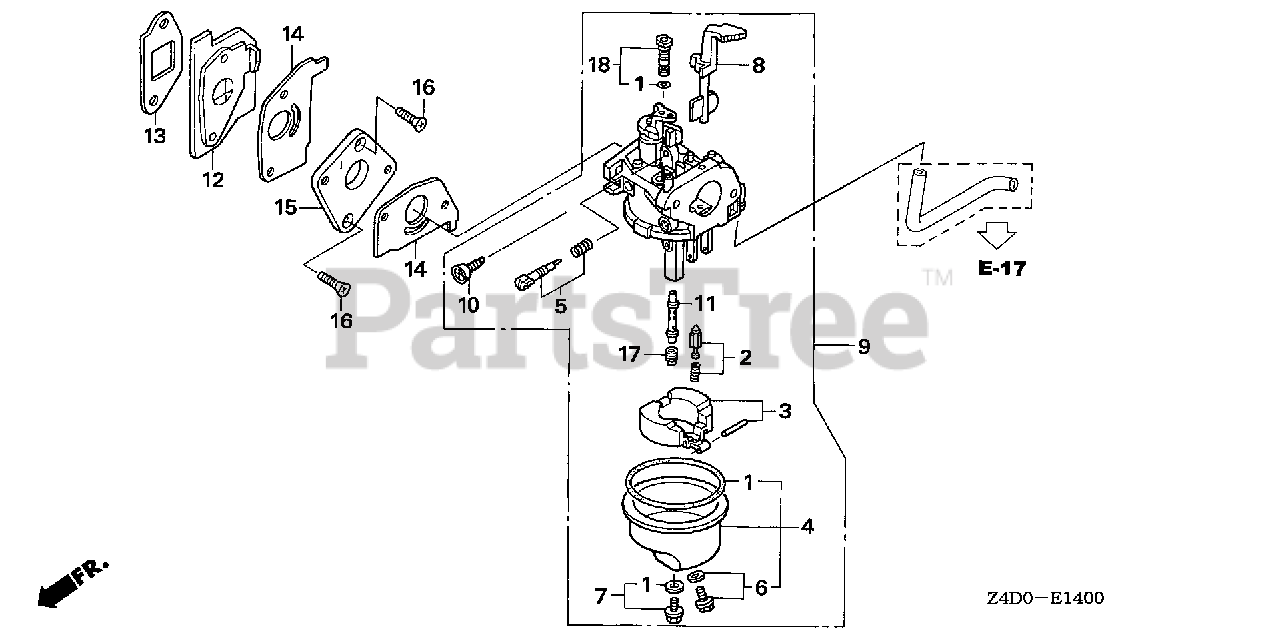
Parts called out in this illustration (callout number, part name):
1	GASKET SET
2	VALVE SET, FLOAT (SEAT NOT INCLUDED)
4	CHAMBER SET, FLOAT
5	SCREW SET, PILOT
6	SCREW SET, DRAIN
7	SCREW SET
9	CARBURETOR ASSY. (BF31D D)
10	SCREW, THROTTLE STOP
11	NOZZLE, MAIN
12	INSULATOR, CARBURETOR
13	GASKET, INSULATOR
14	GASKET, CARBURETOR
15	PLATE, CARBURETOR JOINT
16	SCREW, FLAT (5X20)
17	JET, MAIN (#48)
17	JET, MAIN (#50)
17	JET, MAIN (#52)
18	JET SET, PILOT (#35)
